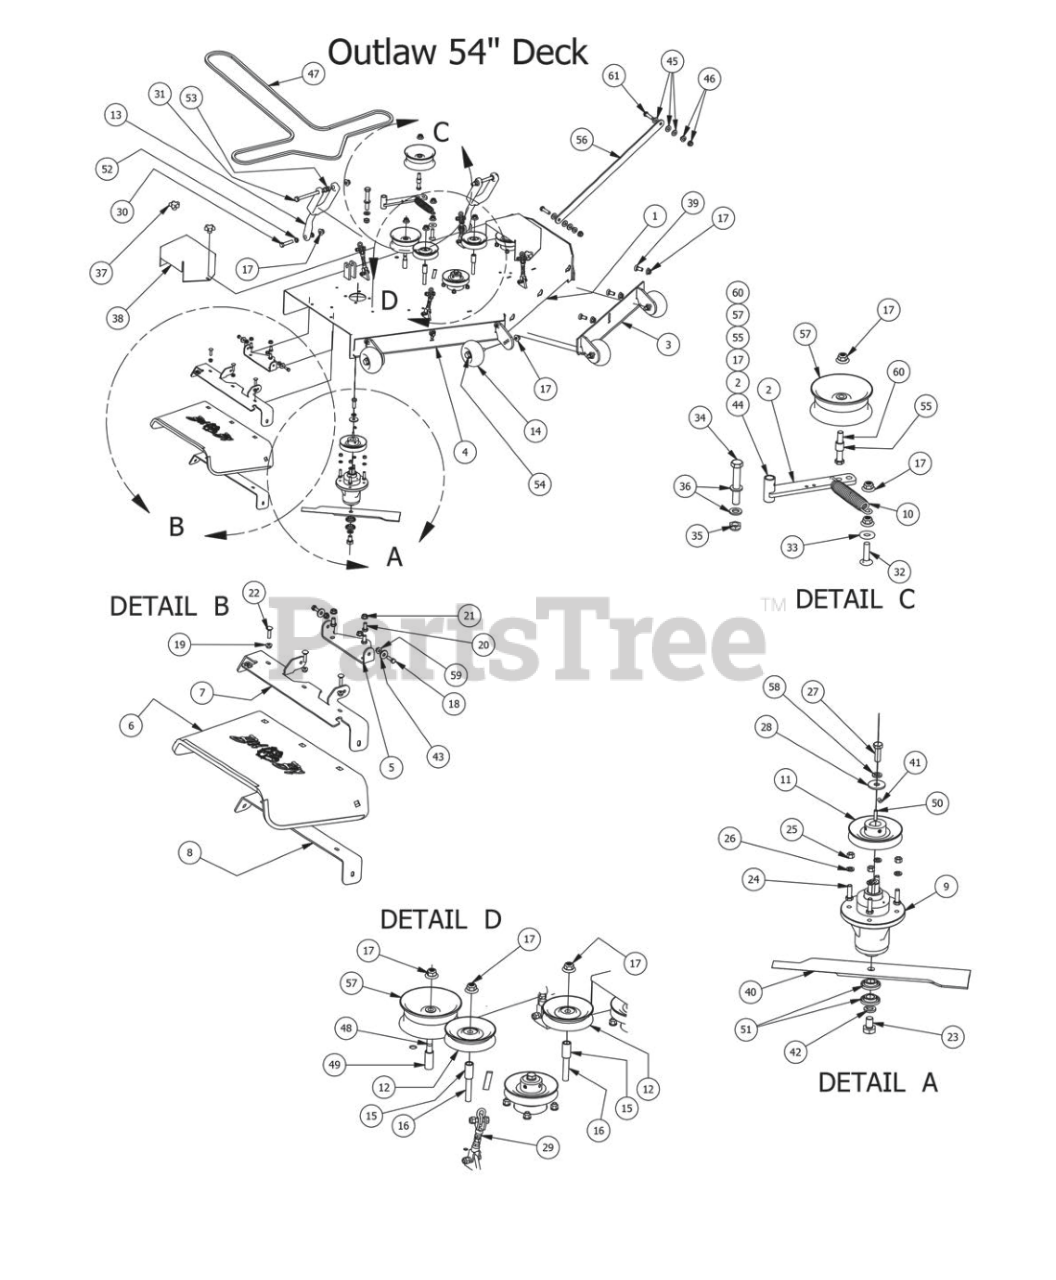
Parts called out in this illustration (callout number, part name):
1	54" Outlaw (Deck Only)
2	Deck Idler Bracket
3	54 Outlaw Adjustable Deck Front (Right)
4	54 Outlaw Adjustable Deck Front (left)
5	Discharge Chute Hanger (deck mounted)
6	Rubber Discharge Chute
7	Dischurge Chute Upper Hanger
8	Lower Hanger
9	Double Bearing Spindle
10	2009 Deck/Pump Idler Spring
11	5" Deck Pulley
12	4 3/4" Idler Pulley
13	Deck Hanger
14	Deck Wheel
15	Pulley Spacer
16	1/2 x 3 1/2 Flange Bolt Grade 8
17	1/2-13 Nylon Flange Nut-Orange
18	5/16" x 1" Bolt
19	5/16" Flange Nut
20	3/8" x 3/4" Hex Bolt
21	3/8" Flange Nut
22	5/16" x 1 1/4" Carriage Bolt
23	5/8" x 1 1/2" Grade 8 Bolt
24	3/8" x 1 1/4" Hex Bolt
25	3/8-16 Hex Nuts Zinc
26	3/8" Lock Washer
27	1/2"-20 x 1 1/2 - Grade 5 Fine Thread Bolt
28	1/2 Belleville Washer
29	2-Link Adjustable Deck Hange
30	1/2-13X 2-1/4 GR Hex Bolts
31	1/2" x 5 1/2" Bolt
32	1/2 x 2" Carriage Bolt
33	1/2" Flat Washer
34	5/8" x 4" Hex Bolt
35	5/8" Nylock (1/2 Jam)
36	.635 ID Plastic Washer
37	5/16" Knob
38	Pulley Cover
39	1/2" x 1 1/4 Carriage Bolt
40	54" Deck Fusion Blade For Outlaw
41	5/16 Set Screw
42	5/8" Lock Washer
43	.360 ID Plastic Washer
44	Deck Idler Assembly Componets 2,17,55,57,60
45	.505 Nylon Spacer
46	1/2" Flange Nut
47	B165 Belt-60 54" deck Outlaw
48	1/2" x 4" Bolt (Grade 8)
49	1 3/4" Pulley Spacer
50	1/4" x 1" Key
51	Double Bearing For Spindle
52	Flange for Lower Deck Arm
53	Flange Bushing for Deck Arm Upper
54	Deck wheel Bolt-2011 Outlaw
55	3/4 OD x 1/2 ID x 3\4 Length
56	Panhard Linkage Bar
57	5 3/4" Deck Idler Pulley
58	1/2" Lock Washer
59	5/16" Nylon Flange Nut
60	1/2-13 x GR 5 Hex Bolt Zinc
61	1/2-13x2 Grade 8 Hex Bolt
